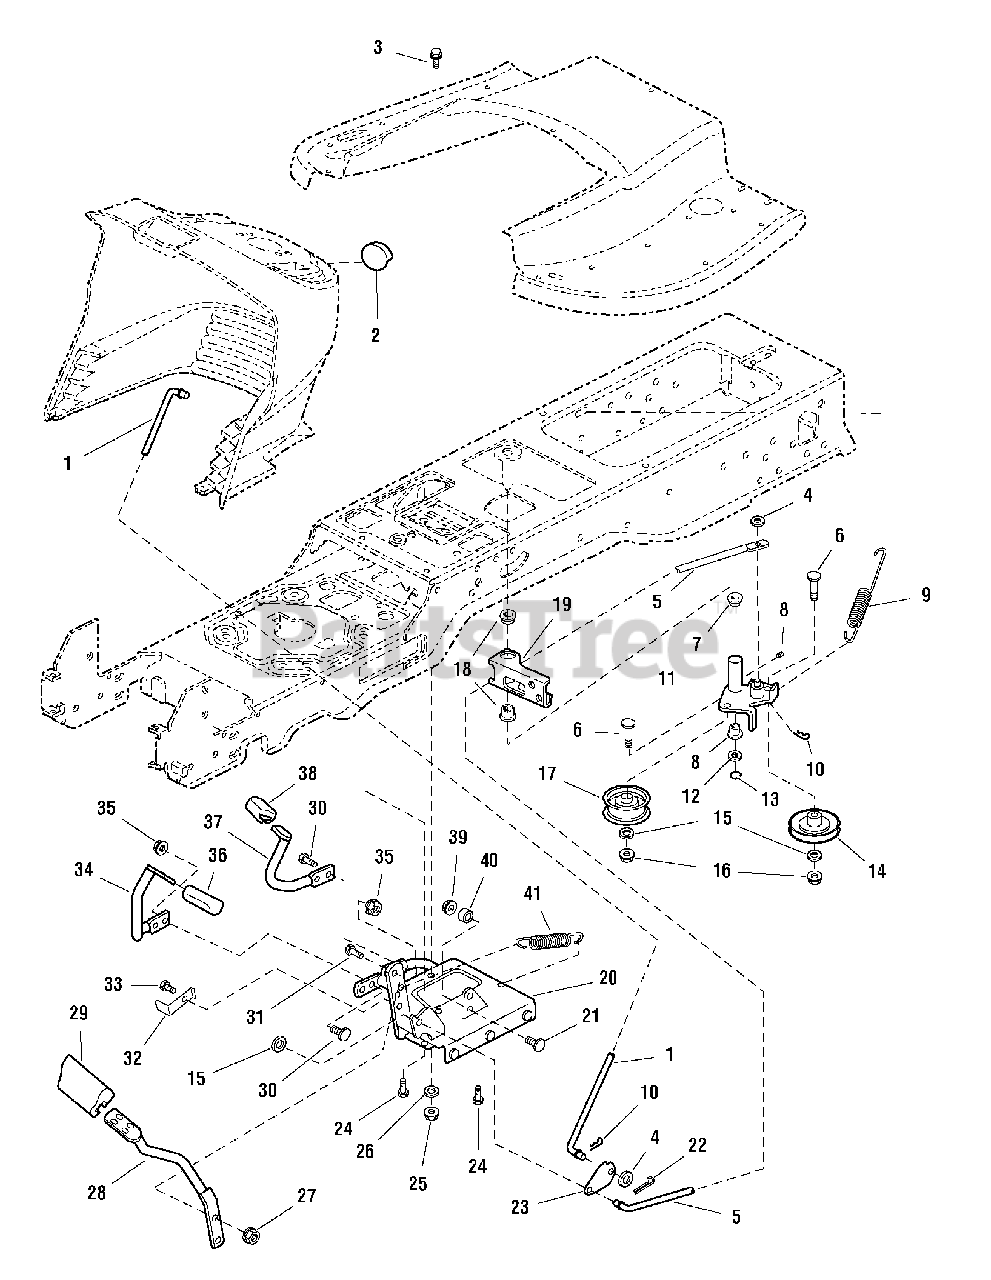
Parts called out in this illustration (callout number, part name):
1	ROD, Brake Lock
2	KNOB, Push On
3	CAPSCREW, Hex Head, Flange Whiz Lock, 5/16-18 x 3/4
4	WASHER, 0.312 (0.34 ID X 0.75 OD X .06THK) BLK
5	ROD, Brake
6	BOLT-RD HD SH SQ NK 3/8-16X1.750 G5 BLK
7	BUSHING
8	FITTING, Lube 1/4 Drive, No Check Ball
9	SPRING, Extension
10	HAIR PIN, .080 Wire x 1.19 LG x .25/.38 Dia
11	ARM & HUB ASSEMBLY, Idler
12	WASHER, Plain, 5/8 (Early models only)
13	RING, External (Klipring) for .625 Dia. Shaft
14	PULLEY, 3" OD x .378" ID x .75" WD, w/Bearing
15	WASHER, 3/8" Flat
16	NUT, Hex Lock, ESNA Light, 3/8-16
17	PULLEY, IDLER, 2.75 DIA X .376 ID
18	BUSHING, 1 x 1-1/8 x 5/8, Nylon
19	ARM, Brake
20	PEDAL ASSEMBLY, Foot
21	BOLT, Carriage, Short Neck, 1/4-20 x 1-1/4, G5
22	PIN, Cotter, 3/4, Black
23	LATCH, Brake
24	BOLT, 5/16-18 X 3/4" Self Tap
25	NUT, Hex Lock ESNA Light, 5/16-18
26	WASHER-0.312(0.34IDX1.00ODX.13THK)BLK
27	NUT, Hex Whiz Lock Flange, 5/16-18, Large, Black
28	PEDAL, Brake
29	PAD, Brake Pedal
30	BOLT, 5/16-18 x 7/8" Round Head Short Square Neck Carriage, GR5
31	BOLT, 5/16-18 x 1
32	ACTUATOR, Switch 2.53" Long
33	CAPSCREW, Hex Head Washer Taptite, 3/8-16 x 3/4
34	PEDAL, Forward
35	NUT, Keps Lock, 5/16 - 18
36	PAD, Foot Pedal, Forward
37	PEDAL, Reverse
38	PAD, Foot Pedal, Reverse
39	NUT, Hex Lock, ESNA Light, 1/4-20
40	CAM, Roller
41	SPRING, Extension, 5/8 OD x 6-5/8 Long
